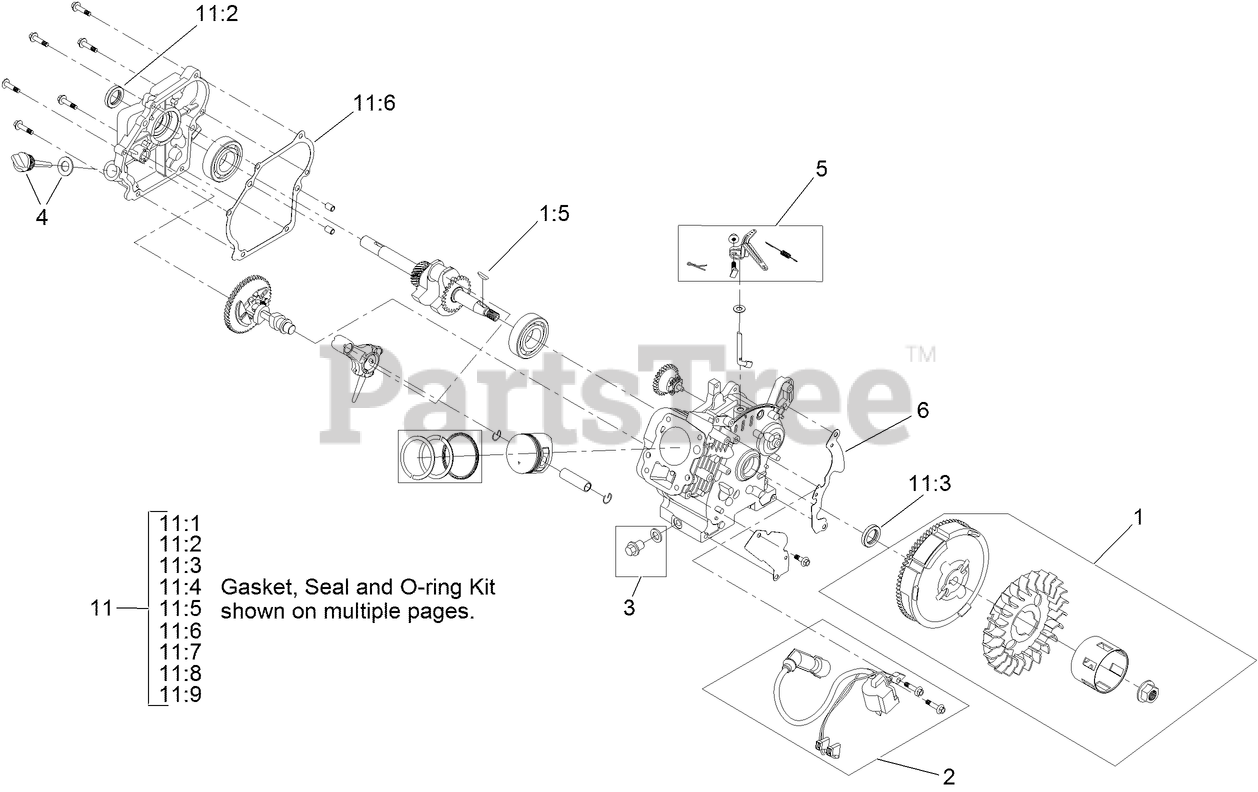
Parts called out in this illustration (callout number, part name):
1	FLYWHEEL KIT
1:5	KEY-WOODRUFF
2	IGNITION KIT
3	DRAIN PLUG KIT
4	DIPSTICK AND O-RING KIT
5	GOVERNOR KIT
6	BLOWER SHROUD KIT
11	GASKET, SEAL AND O-RING KIT
11:1	GASKET-EXHAUST
11:2	SEAL-OIL
11:3	SEAL-OIL
11:4	GASKET-COVER, VALVE
11:5	GASKET-HEAD, CYLINDER
11:6	GASKET-COVER, CRANKCASE
11:7	GASKET-INSULATOR
11:8	INSULATOR-CARBURETOR
11:9	GASKET-CARBURETOR
